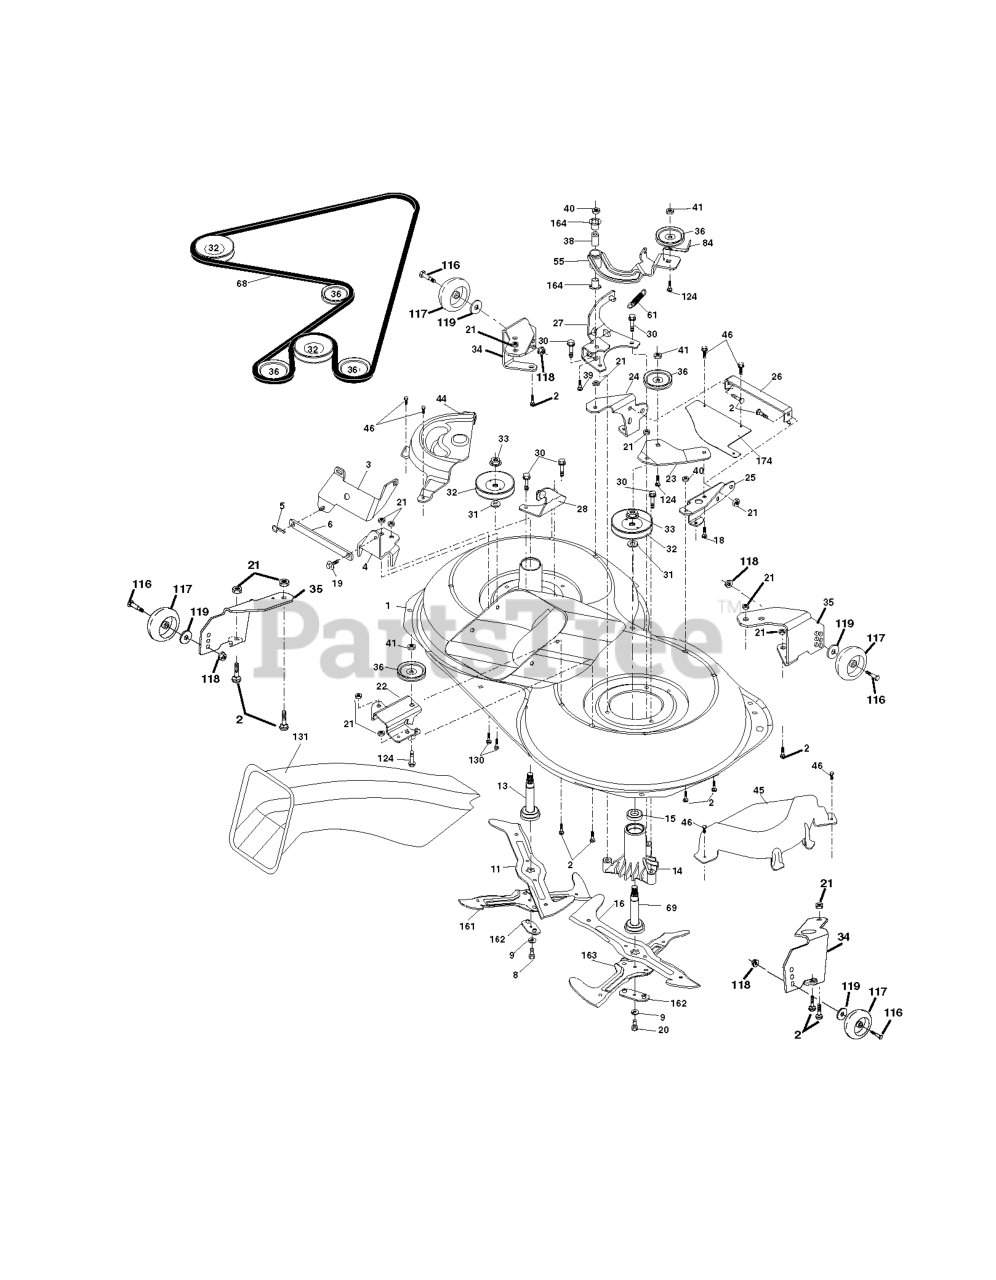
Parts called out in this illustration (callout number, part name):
1	Housing Asm. Mower 107 CRD
2	RP BOLT 5/16-18 X3/4 ZN/YEL GR
5	RETAINER-SPRNG RB
6	BAR.SWAY.92.CRD
8	BOLT.3/8-24X1.25 GR8
9	LOCKWASHER
11	BLADE.3N1.LH.CRD
13	SHAFT ASM VENT
14	HOUSING.MANDREL.VENTED (MACHD)
16	BLADE.3N1.RH.CRD
19	BOLT SHD 5/16-18
20	BOLT.3/8-24X1.25GR8. LHTHRD
21	LOCKNUT
22	BRACKET.IDLER.RR.107.CRD
24	BRACKET
25	BRACKET RF
26	SUPPORT
28	BRACKET
30	SCREW, WASHER HEAD
31	WASHER.SPACER.MANDREL
32	PULLEY.MANDREL.4.80 PD.2006
33	NUT.FLANGE.LOCK.TOP
34	BRACKET
35	BRACKET
36	PULLEY.IDLER.4.25
41	NUT LOCK FLG 3/8-16 UNC
45	COVER.MANDREL.RH.CRD
46	SCREW.1/4-20X5/8
55	ARM.IDLER.107.CRD
61	SPRING
68	HEX-BELT 107 MOWER
69	SHAFT.ASM.W/LWR.BRG.RH.THREAD
84	KEEPER, BELT IDLER
116	BOLT.SHOULDER.3/8-16X3-5/8.
117	RP WHEEL. GUAGE RALLY
118	NUT LOCK FLG 3/8-16 UNC
119	WASHER
124	BOLT.3/8-16X1.50
130	BOLT.CARR.SQNK.5/16-18UNC.X3/4
131	CHUTE BAGGER
163	BLADE.CROSS.RH.CRD.107
164	BRNG T
